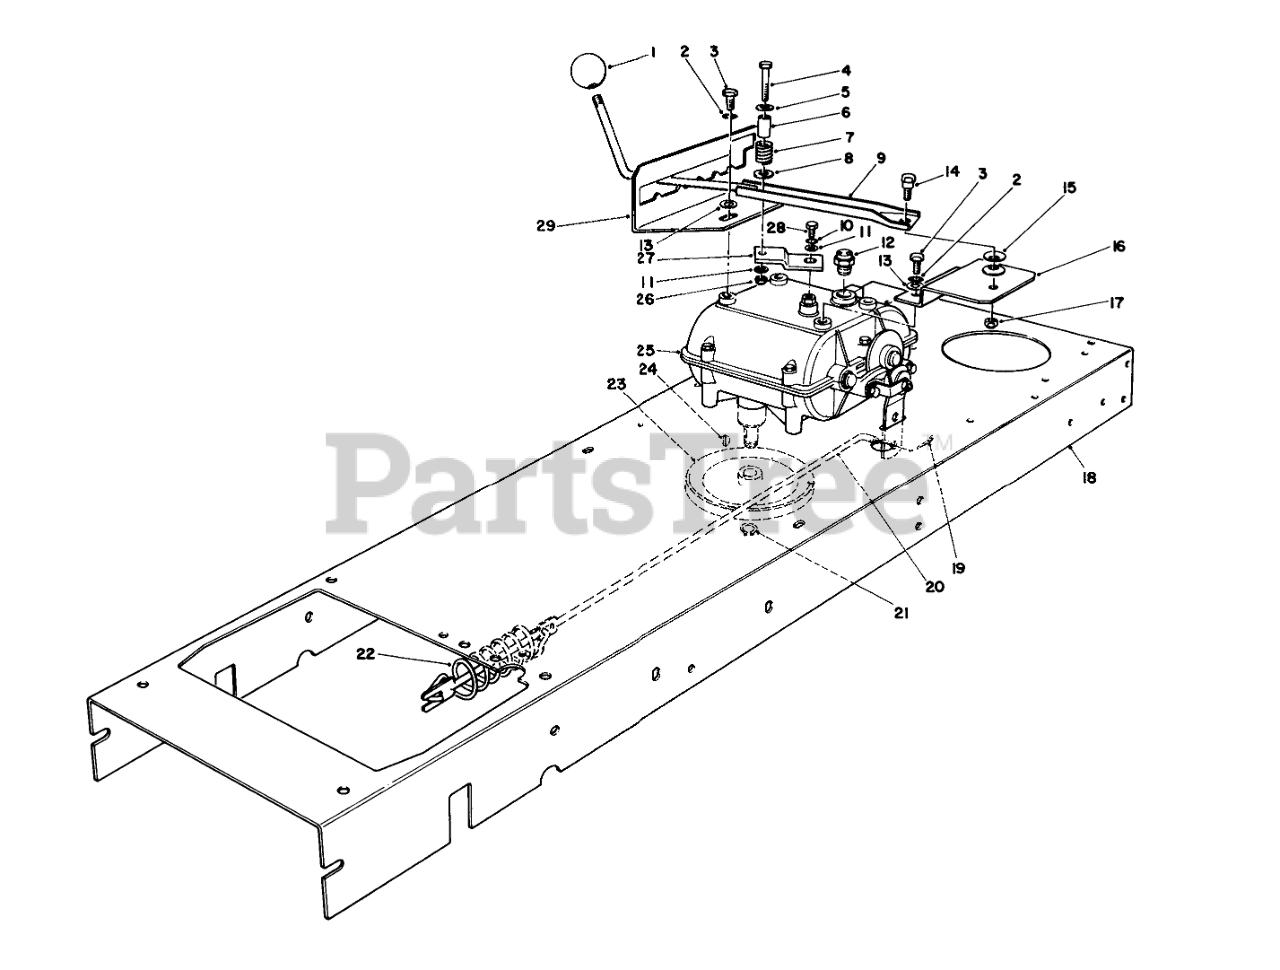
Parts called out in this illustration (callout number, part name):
2	WASHER-LOCK
3	SCREW-HWHTF
4	SCREW-HH
5	WASHER-FLAT
6	SPACER-SPLIT
7	SPRING-COMPRESSION
8	WASHER-FLAT
9	SHIFT LEVER WA B
10	WASHER-LOCK
11	WASHER-FLAT
12	NEUTRAL SWITCH
13	WASHER-PLAIN
14	SCREW-SHOULDER
15	WASHER-BELLEVILLE
16	SHIFT MTG BRKT
17	NUT-LOCK, NI
18	Frame-Main
19	PIN-COTTER
20	BRAKE ROD
21	RING-SNAP, EXTERNAL
22	SPRING-EXT
23	PULLEY
24	KEY-WOODRUFF
25	TRANSMISSION
26	NUT-LOCK, CONE
27	LEVER-SHIFT
28	SCREW-HH
29	Gate-Shift
